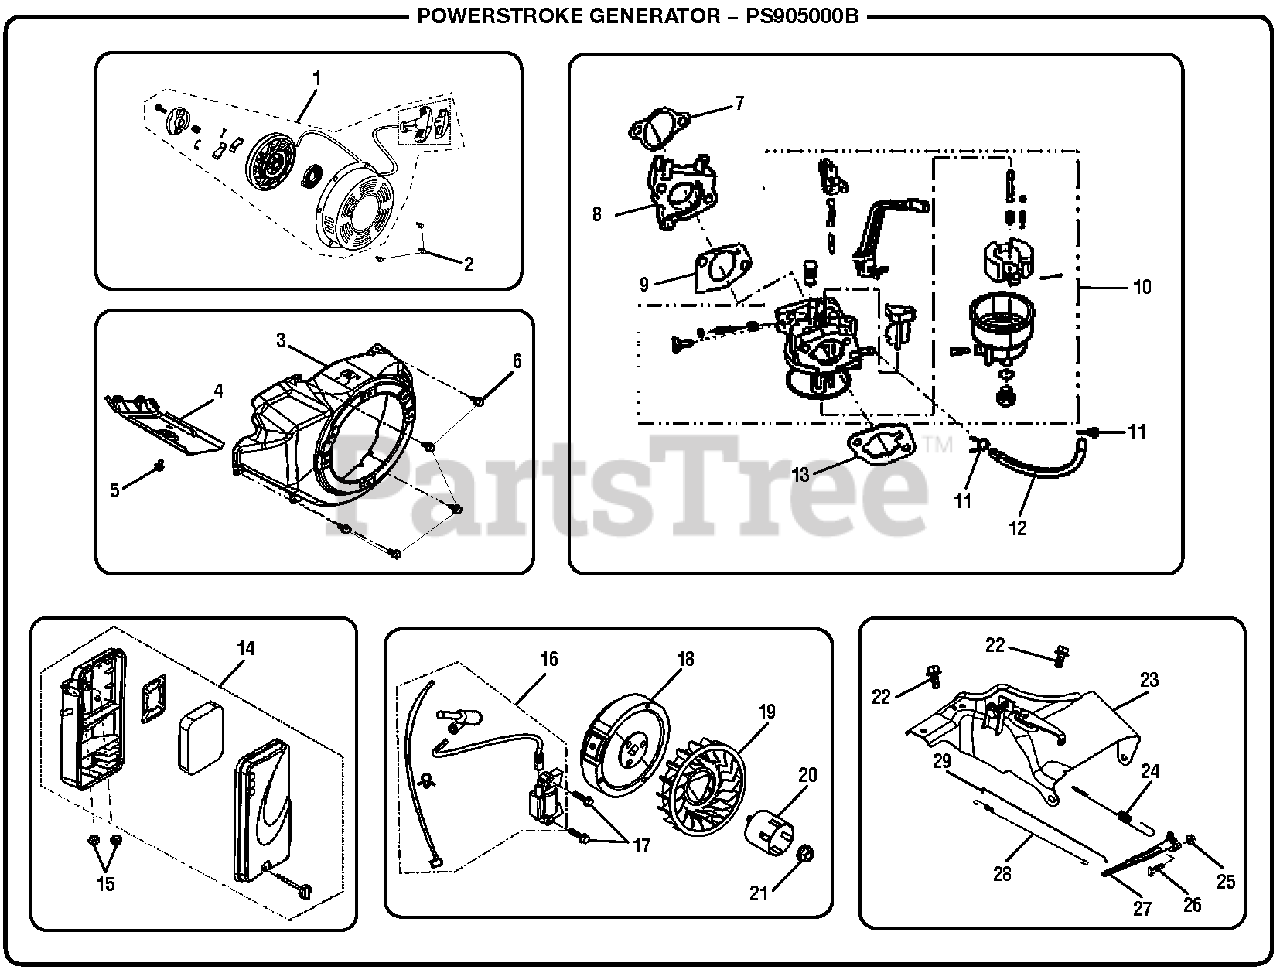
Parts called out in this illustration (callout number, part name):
1	Recoil Starter Assembly
4	Cylinder Body Shroud
7	Inlet Gasket
8	Carburetor Insulator Plate
9	Carburetor Gasket
10	Carburetor Assembly
13	Air Cleaner Gasket
14	Air Cleaner Assembly
16	Ignition Coil
18	Flywheel Assembly
20	Starter Pulley
21	Flywheel Nut
23	Throttle Control Assemby
24	Governor Spring
26	Bolt
27	Governor Support Assembly
28	Throttle Valve Return Spring
29	Governor Rod
